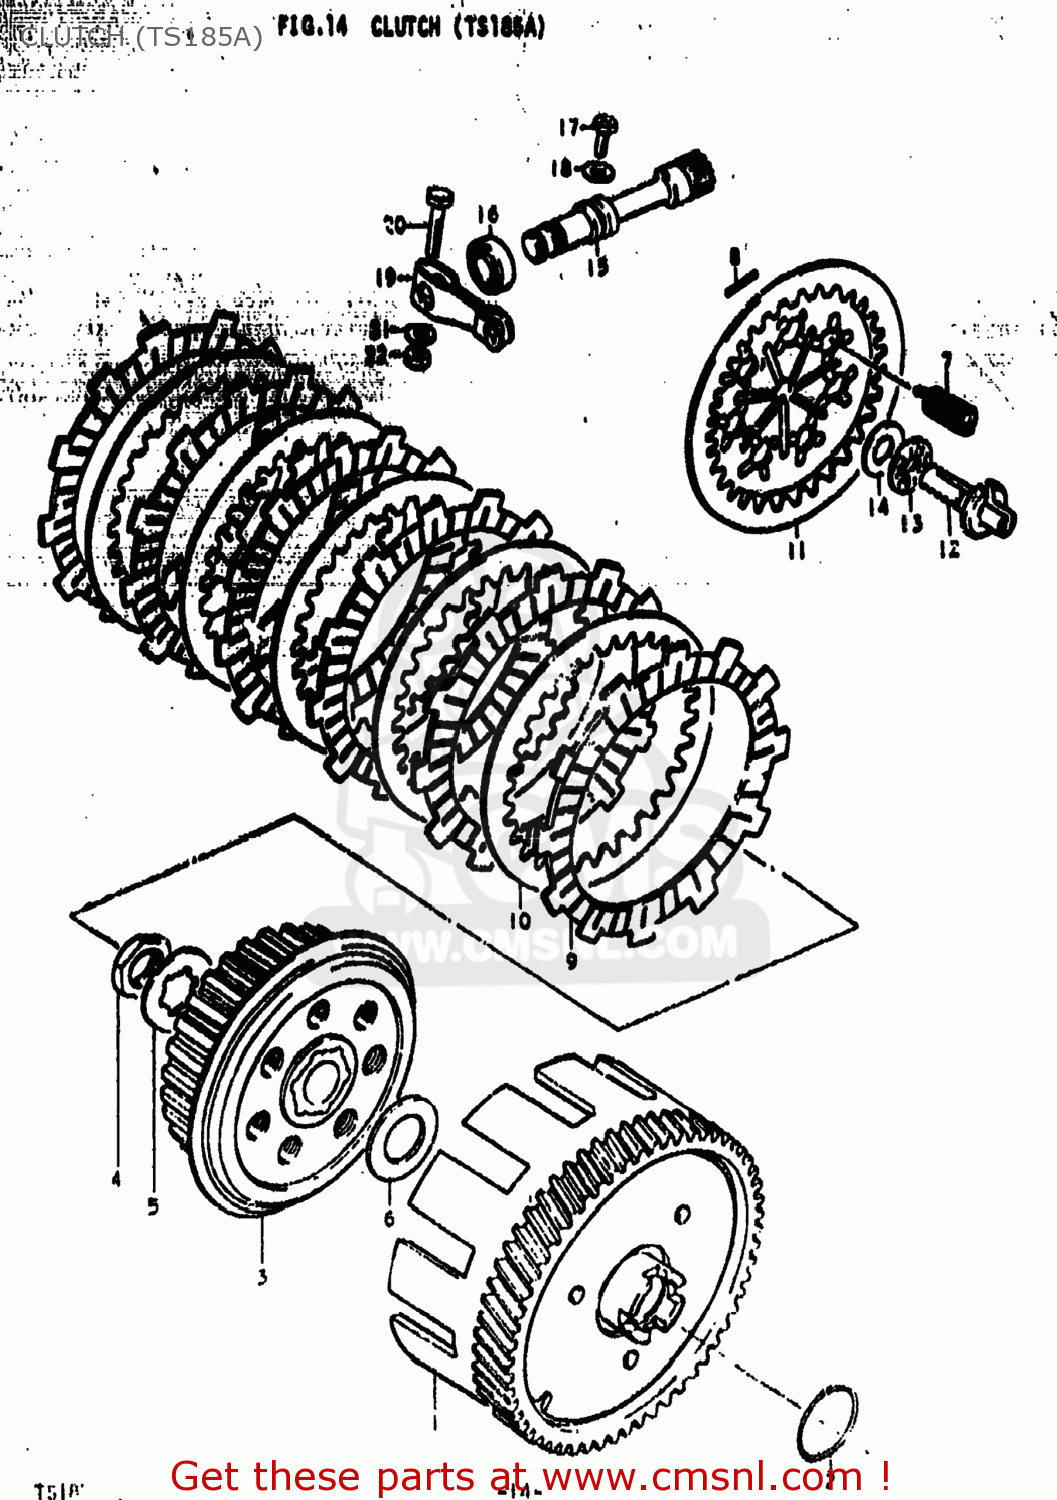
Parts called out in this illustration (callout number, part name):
1	GEAR ASSEMBLY,PRIMARY DRIVE
2	SPRING
3	HUB,CLUTCH SLEEVE
4	NUT
5	WASHER,LOCK
6	WASHER
7	SPRING
8	PIN(2.5X19.8)
9	PLATE,CLUTCH DRIVE
10	PLATE,CLUTCH DRIVEN (NAS)
11	PLATE,CLUTCH PRESSURE
12	RACK,CLUTCH RELEASE
13	BEARING(10X22X2.8)
14	WASHER(10.1X21.4X0.8)
15	PINION,CLUTCH RELEASE
16	OIL SEAL
17	BOLT(6X12)
18	WASHER
19	ARM,CLUTCH RELEASE
20	BOLT
21	WASHER
22	NUT
